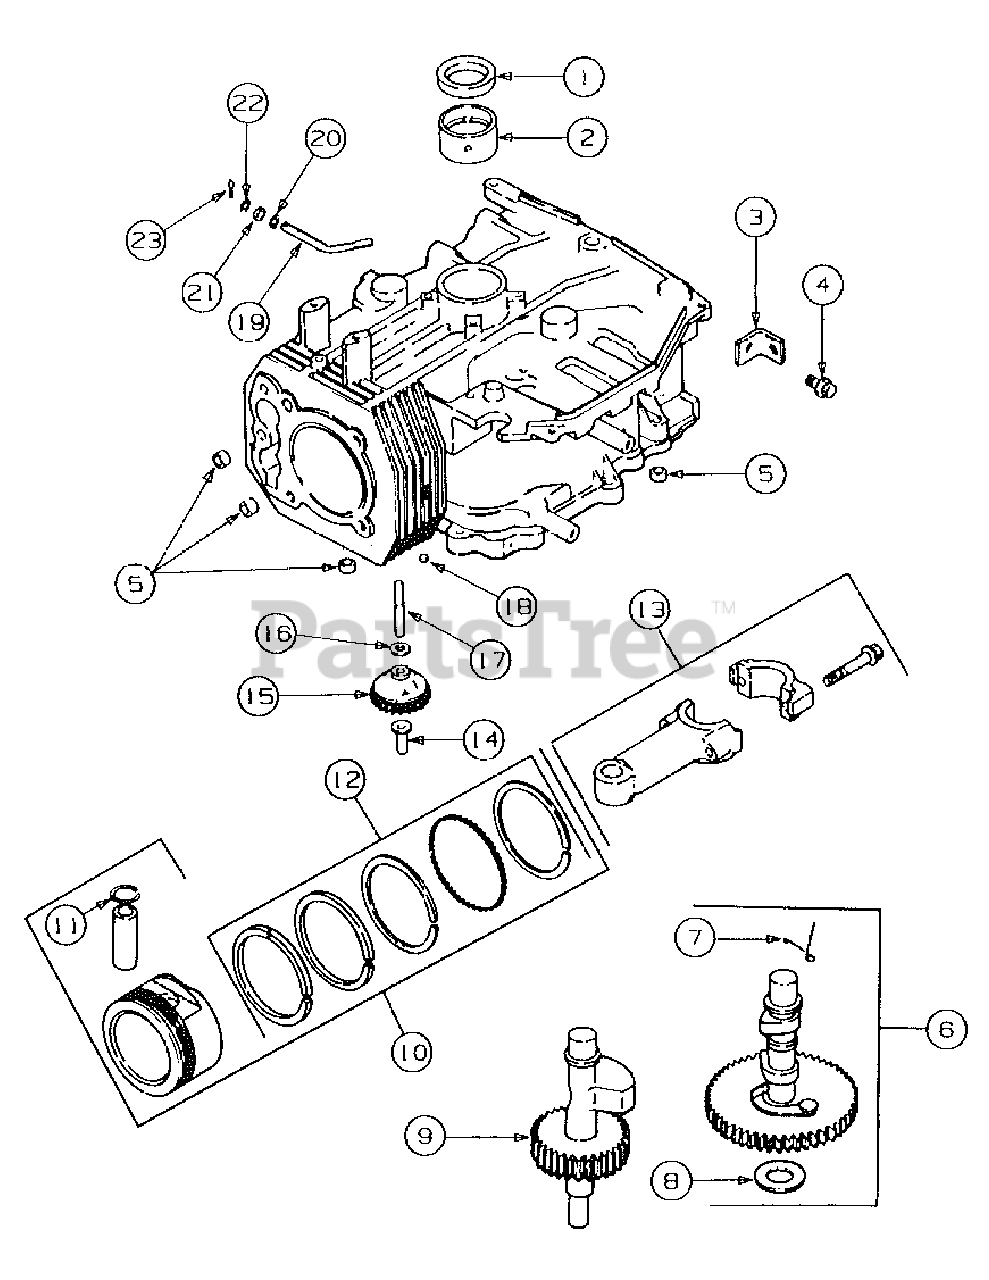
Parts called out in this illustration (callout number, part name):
1	Seal, Crankshaft
2	Bearing, Crankshaft(std)
2	Bearing Crankshaft(.25)
2	Bearing, Crankshaft(.50)
3	Strap, Lifting
4	Screw, Lifting Strap
5	Dowel, Locating
6	Camshaft Ass'y
7	Spring, Actuating
8	Shim, Camshaft, .0280
8	Shim, Camshaft, .300
8	Shim, Camshaft, .320
8	Shim, Camshaft, .340
8	Shim, Camshaft, .360
8	Shim, Camshaft, .380
8	Shim, Camshaft, .400
9	Shaft Balance
10	Piston w/ Ring Set (std)
10	Piston w/Ring Set (.25)
10	Piston w/RIng Set (.50)
11	Retainer, Piston Pin
12	Ring Set (std)
12	Ring Set (.25)
12	Ring Set (.50)
13	Rod, Connecting (std)
13	Rod, Connecting (.25)
14	Pin, Governor Regulating
15	Gear, Governor Ass'y
16	Washer, Governor Gear Thrust
17	Shaft, Governor Gear
18	Plug, Cup
19	Shaft, Governor Cross
20	Washer, PLain 1/4
21	Seal, Governor Cross Shaft
22	Washer, Governor Shaft
23	Pin, Governor Hitch
